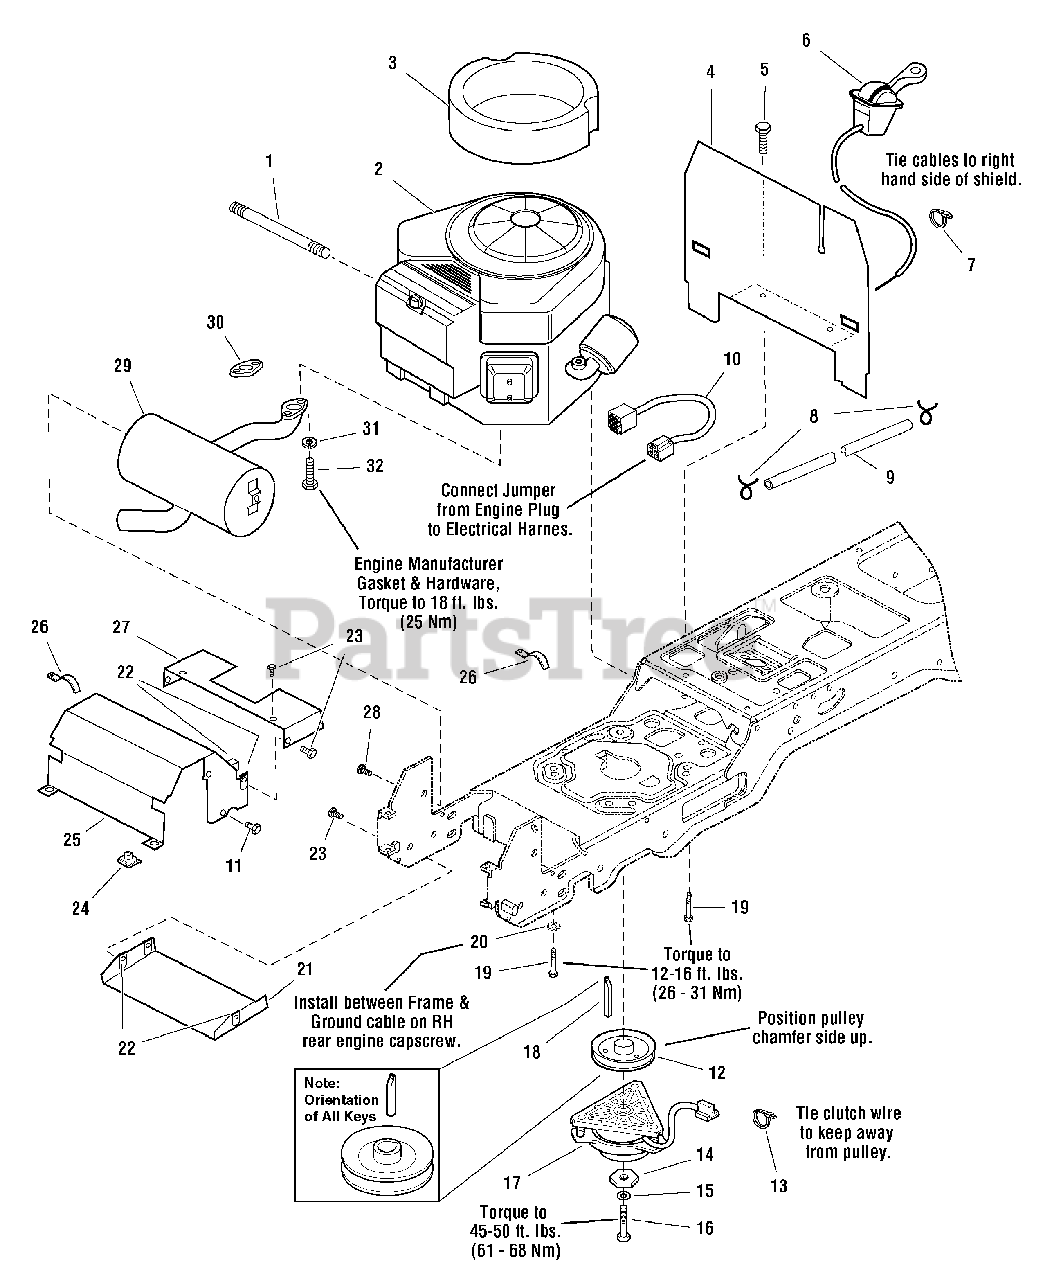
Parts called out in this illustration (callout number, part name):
1	HOSE, Oil Drain, 10 1/2 Long, 3/8-18 Fittings
3	SEAL, Circle
5	CAPSCREW, Hex Washer Head Taptite, 1/2-20 x 1/2, Black
6	CONTROL, Throttle Single 25-3/4" Long w/Knobs
7	TIE, Wire, 7-5/16" Long
8	CLAMP, Hose Type E
9	HOSE, Fuel, 59" Long
10	HARNESS, Wire, Jumper
11	CAPSCREW, Hex Washer Head Taptite, 1/4-20 x 3/8
12	PULLEY & HUB ASSEMBLY
13	TIE, Self Locking, 3-5/8 Long
14	WASHER, Hex, 7/16, Black
15	LOCKWASHER, 7/16
16	CAPSCREW, Hex Head, 7/16-20 x 3-3/4
17	CLUTCH, Electric
18	KEY, HI PRO, 1/4 x 2-1/2
19	CAPSCREW, Hex Washer Head Taptite, 3/8-16 x 1
20	LOCKWASHER, External Tooth, 5/16
21	SHIELD, Muffler Bottom
22	NUT, Speed, 1/4-20, Lug
23	CAPSCREW, Hex Flange Whiz Lock, 1/4-20 x 5/8
24	NUT, Speed, 5/16-18, Lug, Black
25	DUCT, Muffler Top
26	CLIP, Wire 1/8
27	DUCT, Muffler Extension
28	CAPSCREW, Hex Washer Head Taptite, 5/16-18 x 1/2 Black
29	MUFFLER, Kohler, Single
30	GASKET, Kohler, Single
31	LOCKWASHER, 5/16
